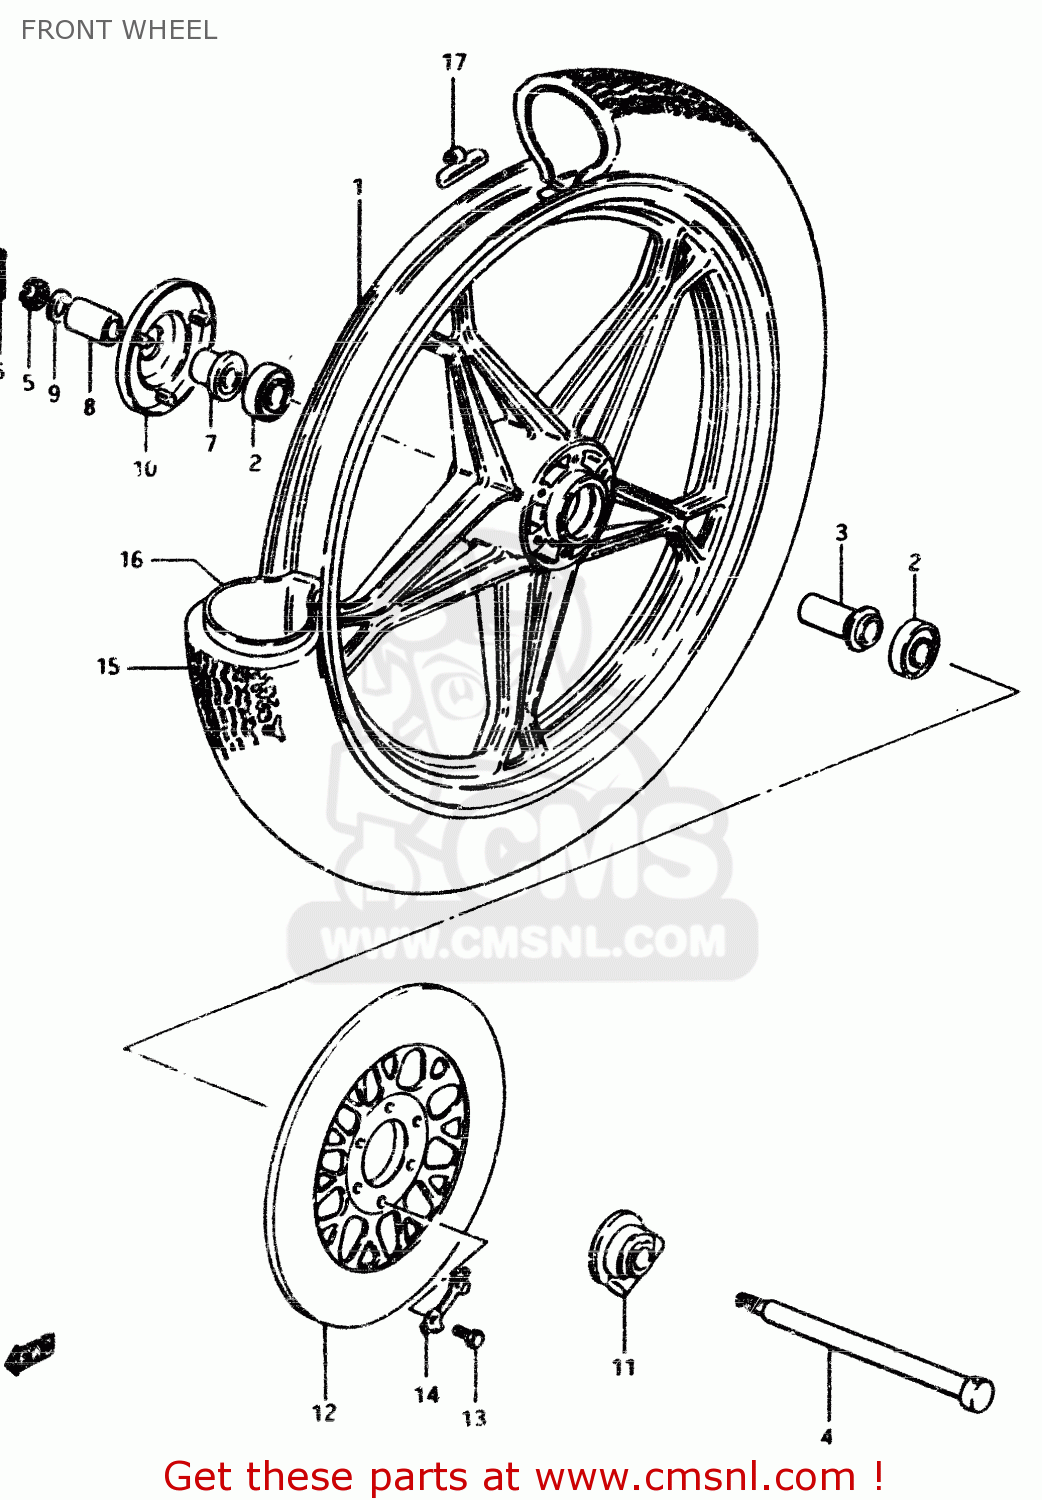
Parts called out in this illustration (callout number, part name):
1	CASTING WHEEL,FRONT 1.85
2	BEARING
3	SPACER,FR HUB BEARING
4	AXLE,FRONT
5	NUT 12MM
6	COTTER PIN
7	SPACER,FR HUB BEARING,R
8	SPACER(15X22X30)
9	WASHER
10	COVER,FR HUB,R
11	BOX ASSEMBLY,SPEEDOMETER GEAR
12	DISC,FR BRAKE
13	BOLT(8X25)
14	WASHER
15	TIRE
16	TUBE 2.75-19 070-483MM
17	BALANCER,WHEEL
